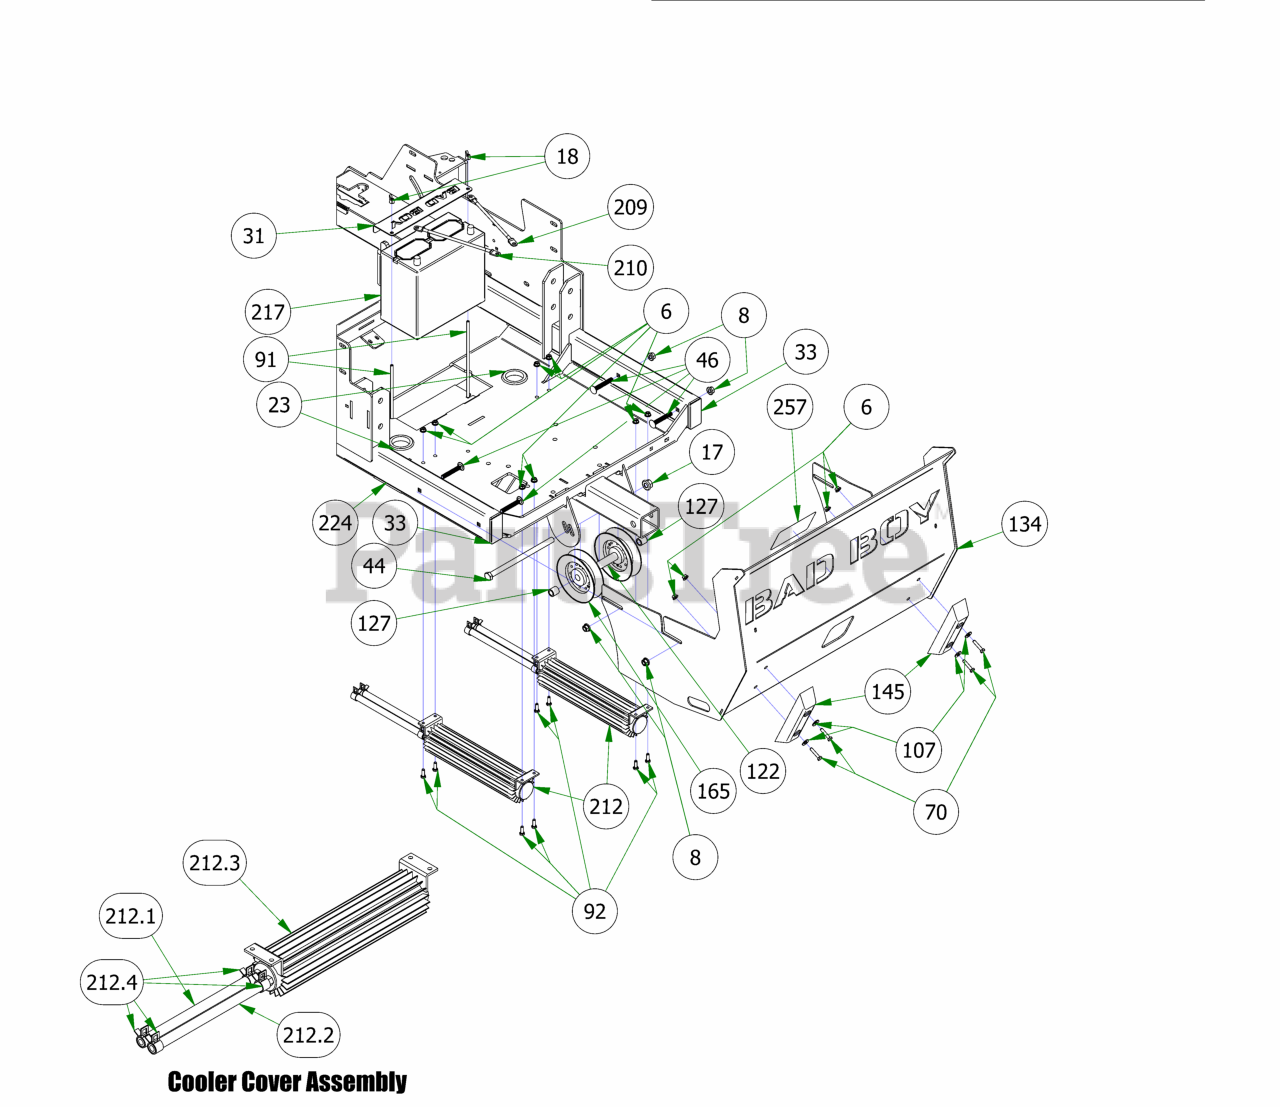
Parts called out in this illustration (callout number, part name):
6	1/4-20 NYL INSERT FLANGE LOCKNUT ZINC
8	3/8-16 NYLON INSERT FLANGE LOCKNUT (GR.F) ZINC
17	1/2-13 NYLON INSERT FLANGE LOCKNUT ZINC
18	1/4-20 WING NUT FORGED (TYPE A) LIGHT SERIES ZINC
23	2019 2" x .25 Rubber Grommet
31	2019 Horizontal Battery Hold Down Cover
33	1 1/2 x 3 Frame Plug
44	1/2-13 X 8-1/2 HEX CAP SCREW (GR.5) ZINC
46	3/8" x 2 1/2" Carriage Bolt
70	1/4-20 X 1-1/4 HEX CAP SCREW (GR.5) ZINC
91	1/4-20 X 9 CARRIAGE BOLT ZINC
92	1/4-20 X 3/4 HEX CAP SCREW (GR.5) ZINC
107	1/4 USS FLAT WASHER (3/4 OD) ZINC
122	2019 Pulley Spacer .75 x .5 x 4.375
127	.51 ID X .75 OD X .75 LGTH SOLID SPACER ZINC
134	2019 Horizontal Suspension Rear Cover
145	8" Rubber Bumper
165	2019 Outlaw Horizontal Rear V Pulley
209	Red Battery Cable - Diesel
210	Black Battery Cable - Diesel
212	Renegade Oil Cooler Assembly
212.1	3/8" Clear Hose
212.2	3/8" Clear Hose
212.3	2019 12" Oil Cooler With Fittings
212.4	3/8" Hose Clamp
217	Battery - Diesel/Renegade Models PF-516
224	2019 Renegade Gas Frame - Powdercoated
257	2019 Renegade Pump Belt Route Decal
